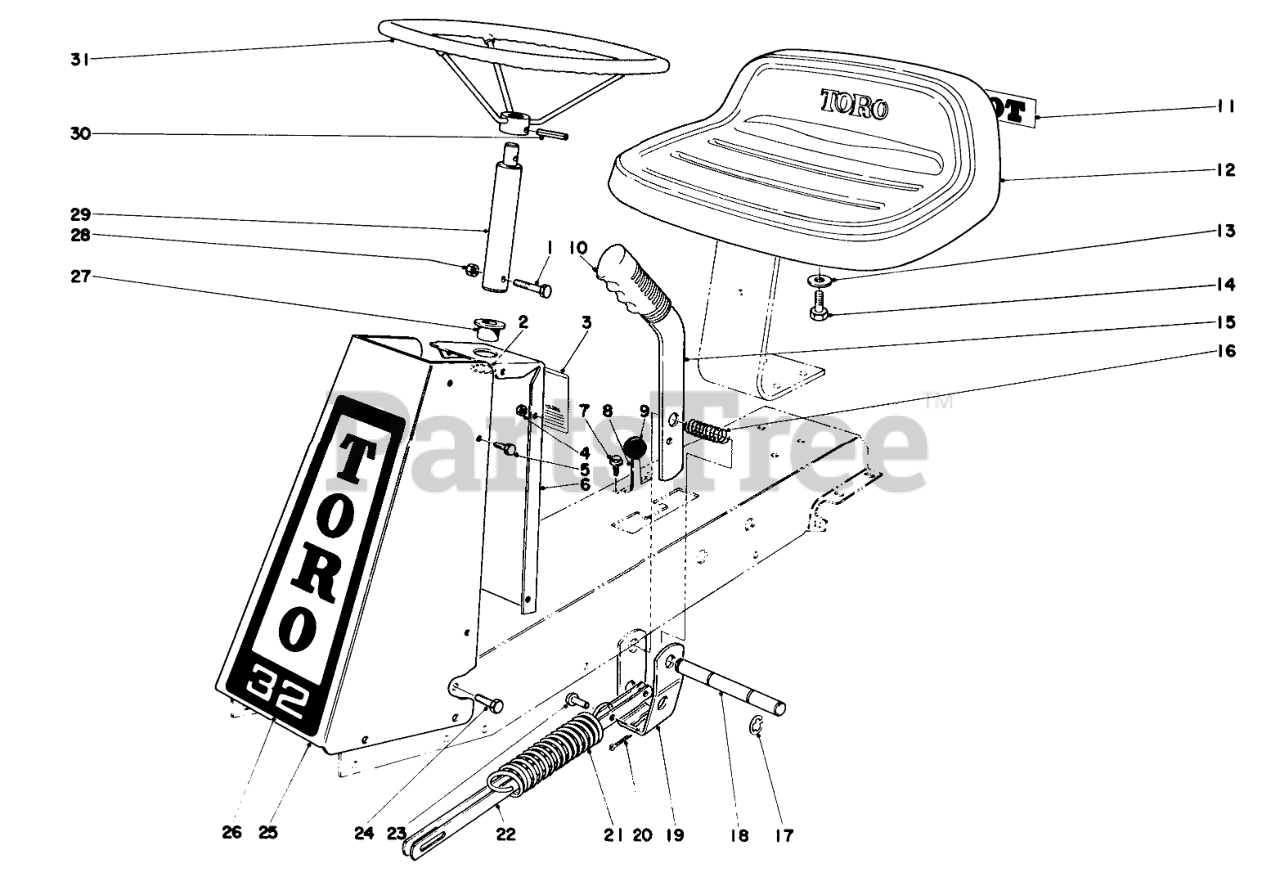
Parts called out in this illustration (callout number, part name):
1	SCREW-HH
2	Retaining Ring
3	Decal-Caution
4	NUT-LOCK, CONE
5	SCREW-HH
6	Panel Assem. (Incl. Ref. Nos. 2 & 27)
7	Screw
8	Throttle Control
9	KNOB-CONTROL
10	Grip Handle
11	Decal
13	WASHER-FLAT
14	HEX HD CAPSCREW
15	Blade Clutch Handle
16	Spring
17	E-RING
18	Blade Handle Shaft
19	Clutch Handle Pivot
20	PIN-COTTER
21	Spring
22	Tie Bar Blade Clutch
23	PIN-CLEVIS
24	SCREW-HH
25	Cover, Steering Column
26	Decal
27	Bushing
28	NUT-LOCK, CONE
29	Shaft Steering
30	PIN-ROLL
31	Steering Wheel
